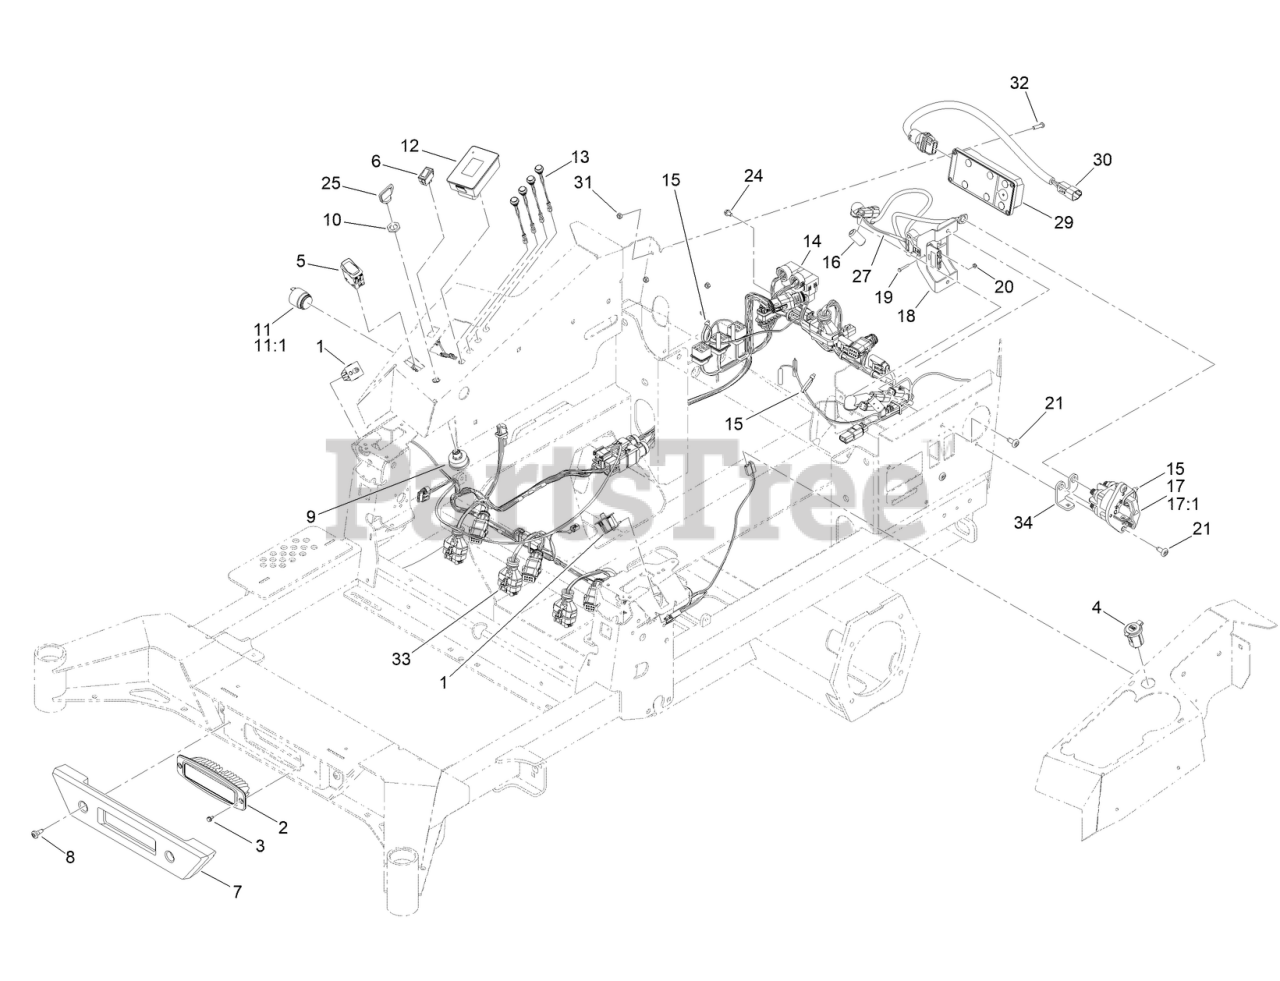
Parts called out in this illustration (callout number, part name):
1	SWITCH-PLUNGER, ON-(ON)
2	MOUNT-FLUSH, LIGHT
3	SCREW-HWH
4	PORT-POWER, USB
5	SWITCH-ROCKER, ON-NONE-ON
6	SWITCH-ROCKER
7	BUMPER-FRONT
8	SCREW-SHOULDER
9	SWITCH-KEY, SPST
11	AUDIO ALARM ASM
11:1	NUT-PLASTIC, KNURLED
12	TDM 2002
13	SWITCH-PUSHBUTTON
14	HARNESS-WIRE, MAIN
15	TIE-CABLE
16	FERRITE, SNAP-ON
17	SWITCH-DISCONNECT
17:1	NUT-HF
18	BRACKET-CHARGER, DUAL
19	SCREW
20	NUT-HEX
24	SCREW-HWH
25	KEY-IGNITION
27	HARNESS-WIRE, CHARGER PORT
29	CONTROLLER, CALAMP-NA
30	HARNESS-WIRE
31	NUT-LOCK
32	SCREW-HSBH
33	HARNESS-WIRE, DECK
34	BUSBAR-2, SWITCH
